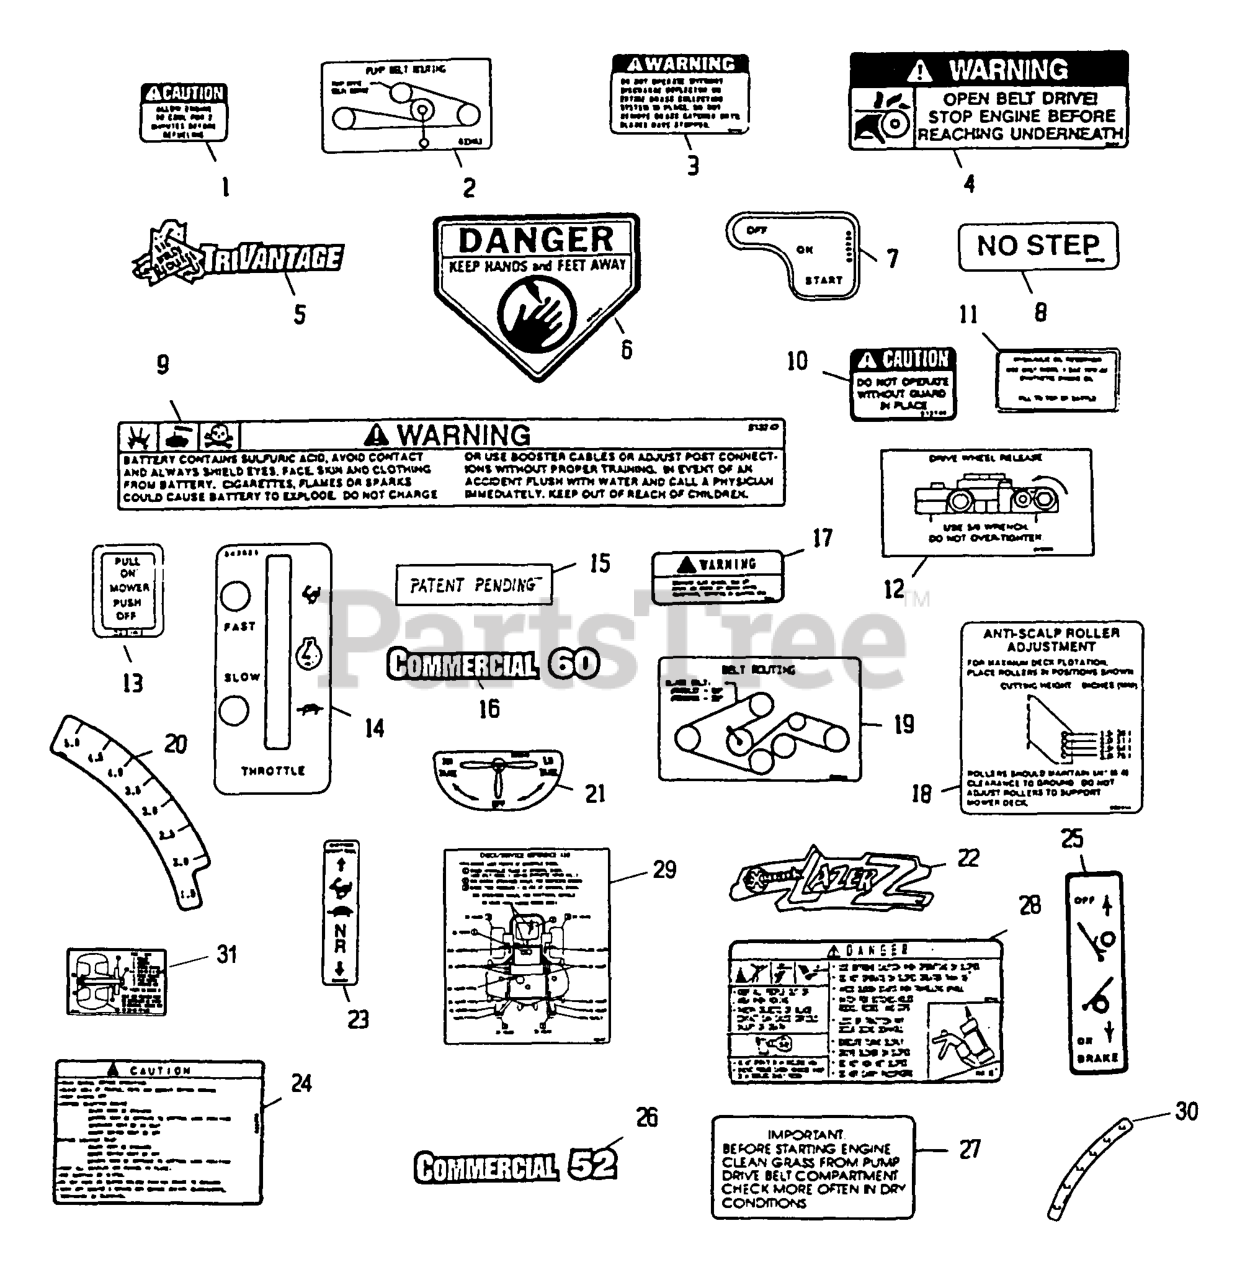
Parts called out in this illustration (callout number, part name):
3	DECAL-WARNING, DISCHARGE
4	DECAL,BELT DRIVE
6	DECAL-DANGER
8	DECAL,NO STEP
9	DECAL-BATTERY
10	DECAL-GUARD
11	DECAL,HYD TANK
15	Decal, Patent Pending
16	DECAL,COMMERCIAL 60
17	DECAL,WARNING
20	DECAL-HEIGHT, DECK
25	DECAL-LAZERZ BRAKE
26	DECAL,COMMERCIAL 52
27	DECAL-IMPORTANT
28	DECAL - DANGER
29	DECAL,CHECK/SERVICE
30	DECAL-HEIGHT, DECK
31	DECAL,ROLLER MOUNTING
